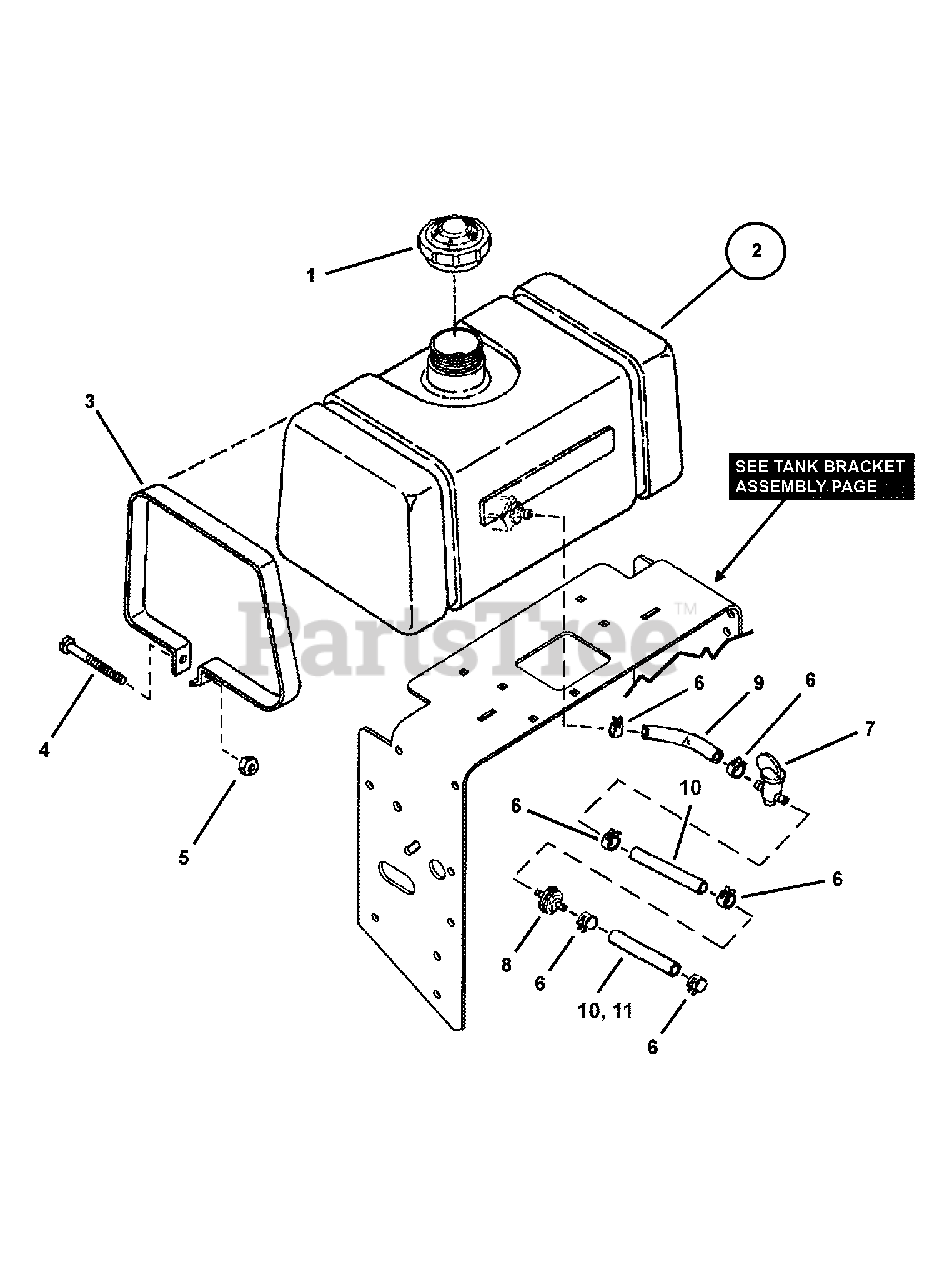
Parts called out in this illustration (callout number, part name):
1	CAP, Fuel Tank
2	FUEL TANK
3	STRAP, Tank
4	SCREW, #10-24 x 2-1/2" Pan Head Machine
5	NUT, #10-24 Hex Nyloc
6	CLAMP, Fuel Hose
7	VALVE, Fuel
8	FILTER, In-Line
9	*HOSE, Fuel (1/4" I.D. x 10" Long)
10	*HOSE, Fuel (1/4" I.D. x 6-1/2" Long)
11	*HOSE, Fuel (1/4" I. D. x " 8-1/2 Long)
